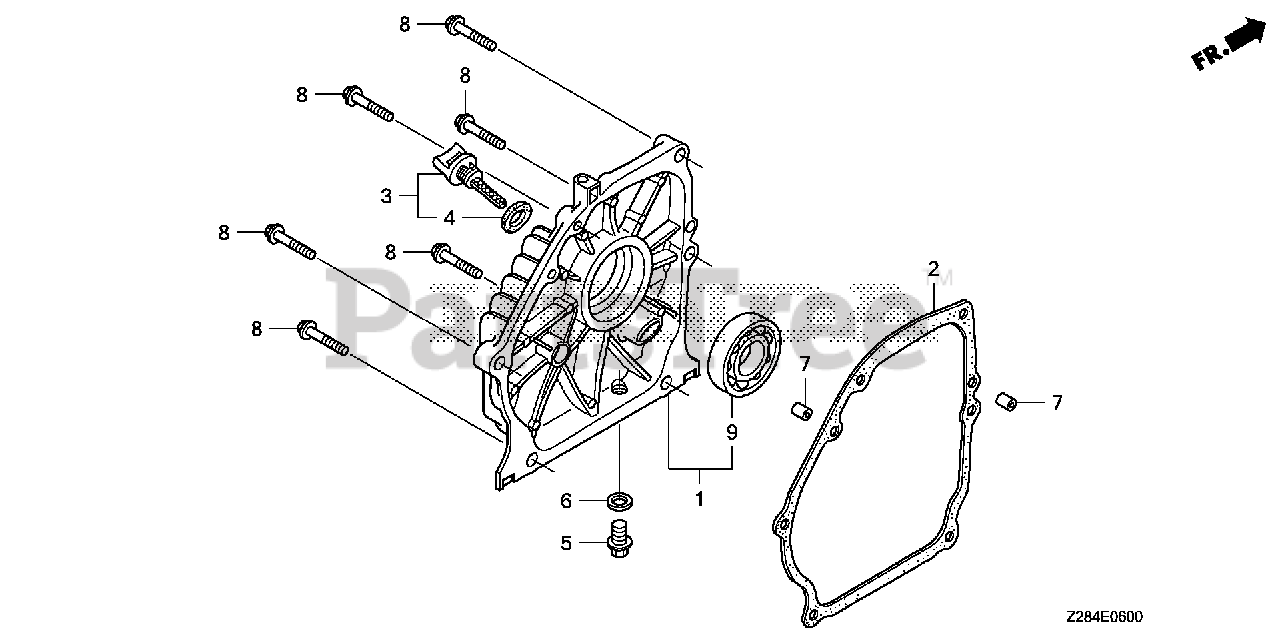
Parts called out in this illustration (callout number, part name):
1	COVER, CRANKCASE
2	GASKET, CASE COVER (NON-ASBESTOS)
3	CAP ASSY., OIL FILLER (GRAY)
4	GASKET, OIL FILLER CAP
5	BOLT, DRAIN PLUG
6	WASHER, DRAIN PLUG (10.2MM)
7	PIN, DOWEL (8X14)
8	BOLT, FLANGE (8X32)
9	BEARING, RADIAL BALL (6205)
